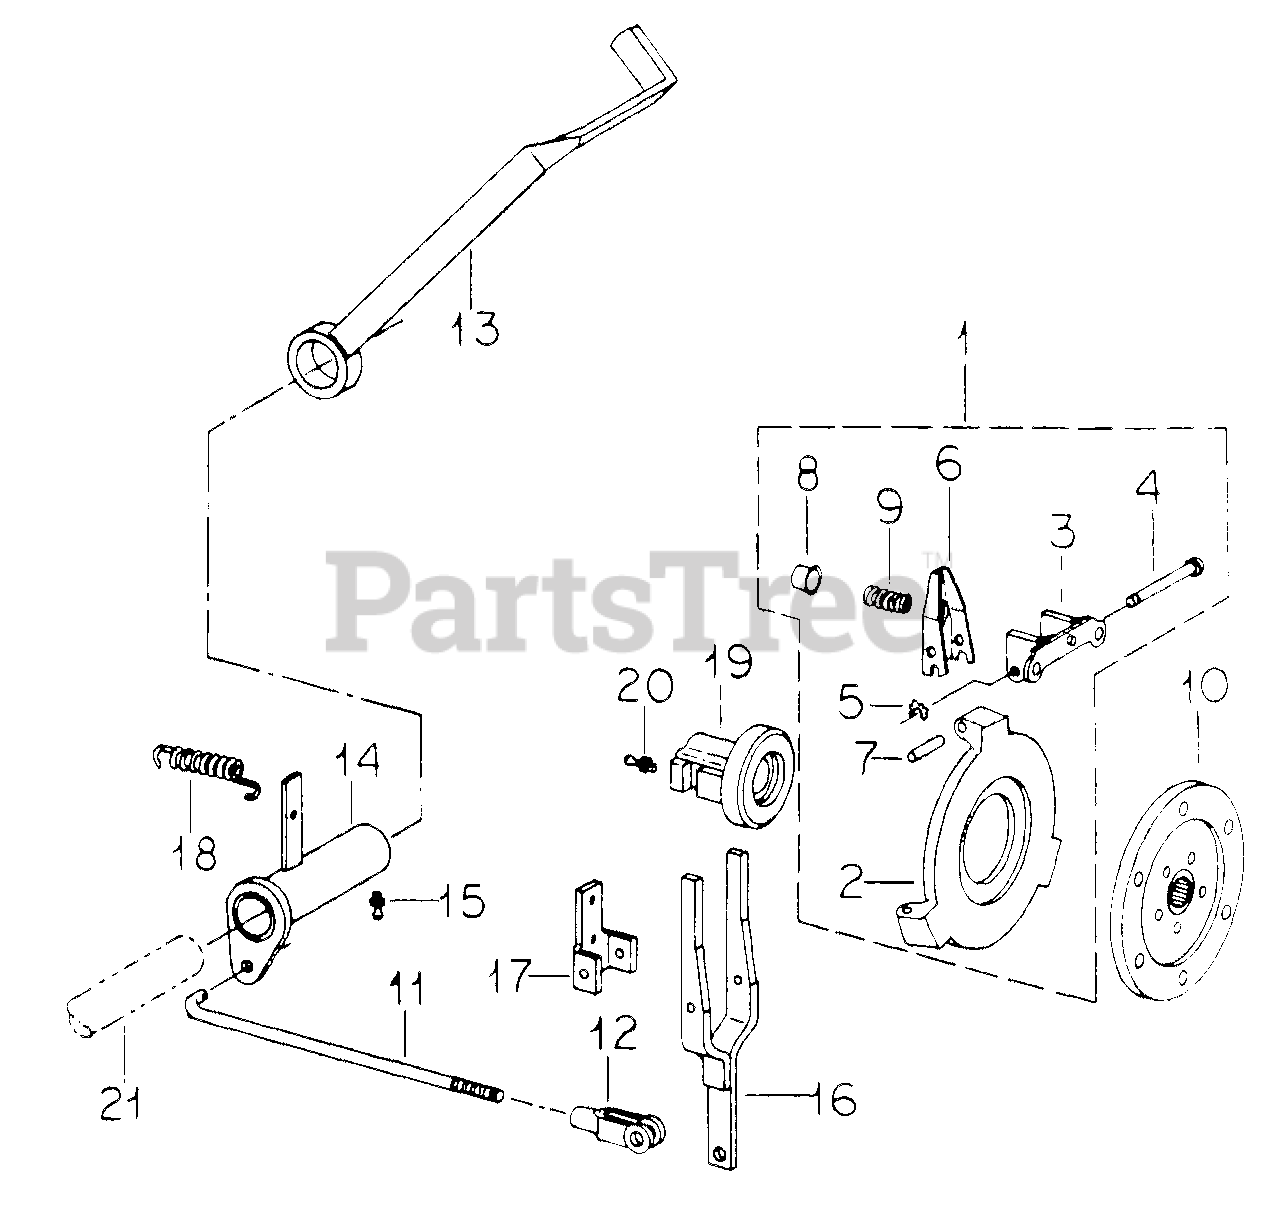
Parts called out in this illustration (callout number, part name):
1	PLATE ASSY, CLUTCH PRESSURE
2	PLATE, PRESSURE
3	BRACKET, LEVER
4	PIN, CLEVIS
6	LEVER RELEASE
7	PIN, PRESSURE PLATE
8	CUP, SPRING
9	SPRING, PRESSURE
10	DISC ASSY, CLUTCH DRIVEN
12	CLEVIS, ROD END
13	PEDAL ASSY. CLUTCH
14	TUBE ASSY, CLUTCH PEDAL
15	FITTING, LUBRICATION
16	YOKE ASSY, CLUTCH
17	BRACKET, CLUTCH YOKE
18	SPRING, CLUTCH RETURN
19	RETAINER ASSY, CLUTCH RLS BRG.
20	FITTING, LUBRICATION
21	SHAFT, BRAKE
